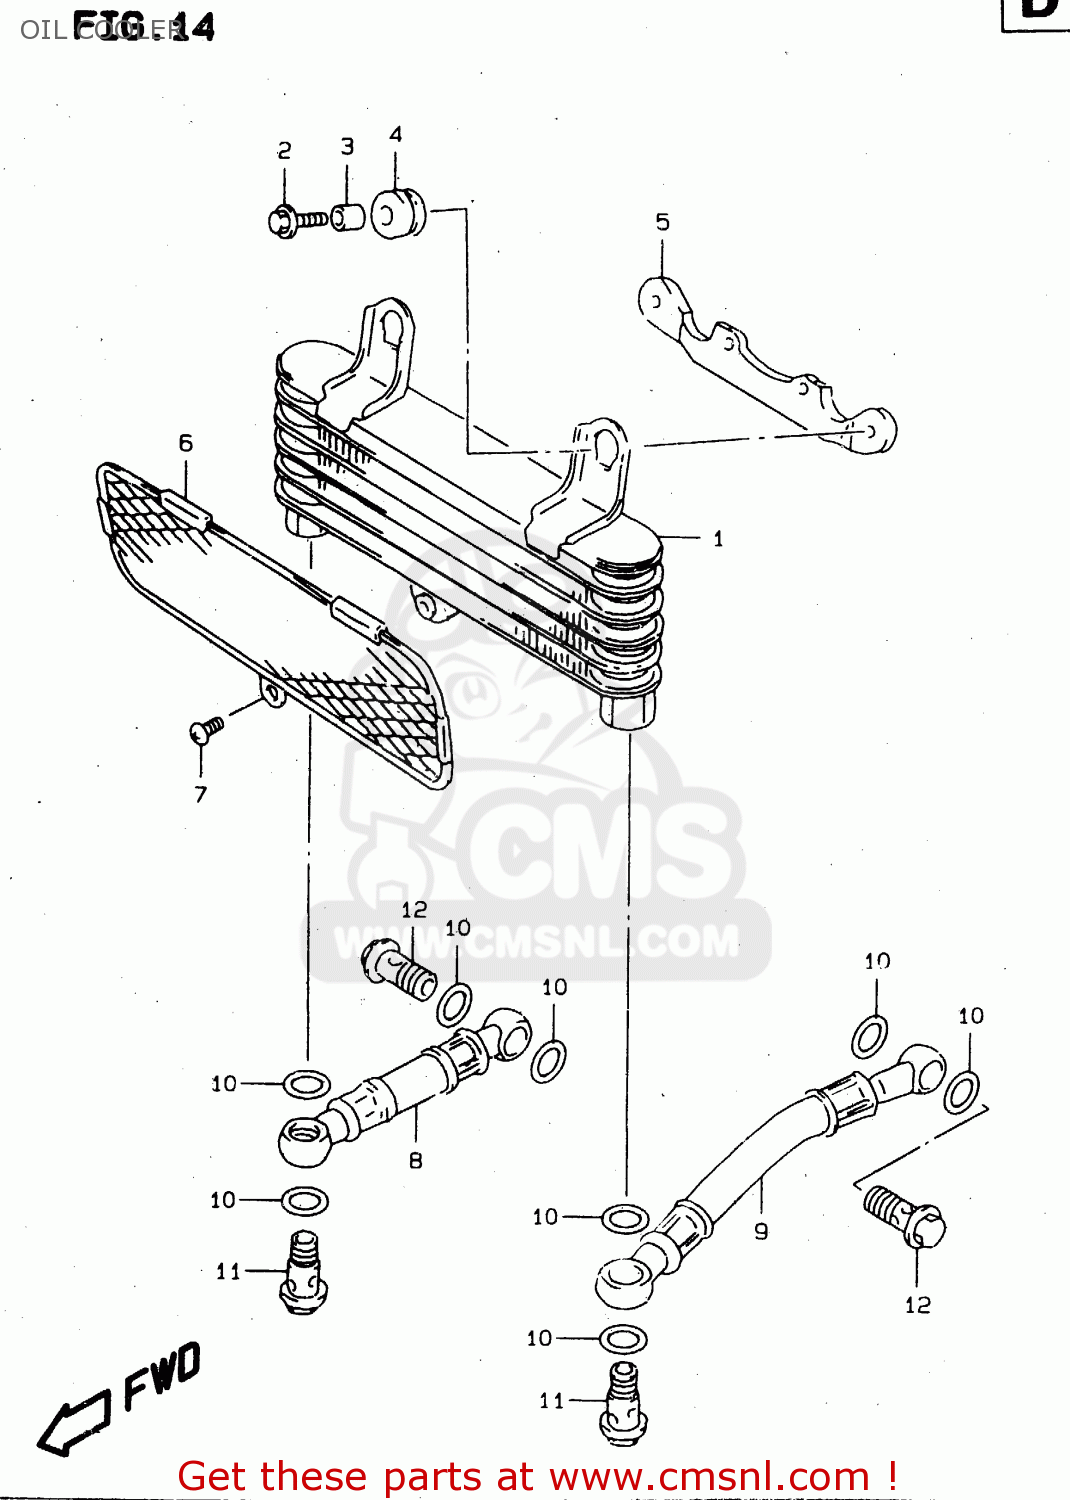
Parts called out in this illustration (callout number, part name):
1	COOLER ASSEMBLY,OIL
2	BOLT 6X20
3	SPACER(6.5X10X10)
4	CUSHION
5	BRACKET,OIL COOLER
6	GUARD,OIL COOLER
7	SCREW
8	HOSE,OIL COOLER,R
9	HOSE COMP,OIL COOLER,LEFT
10	GASKET(14X20X1.5) (NAS)
11	BOLT UNION
12	BOLT UNION
